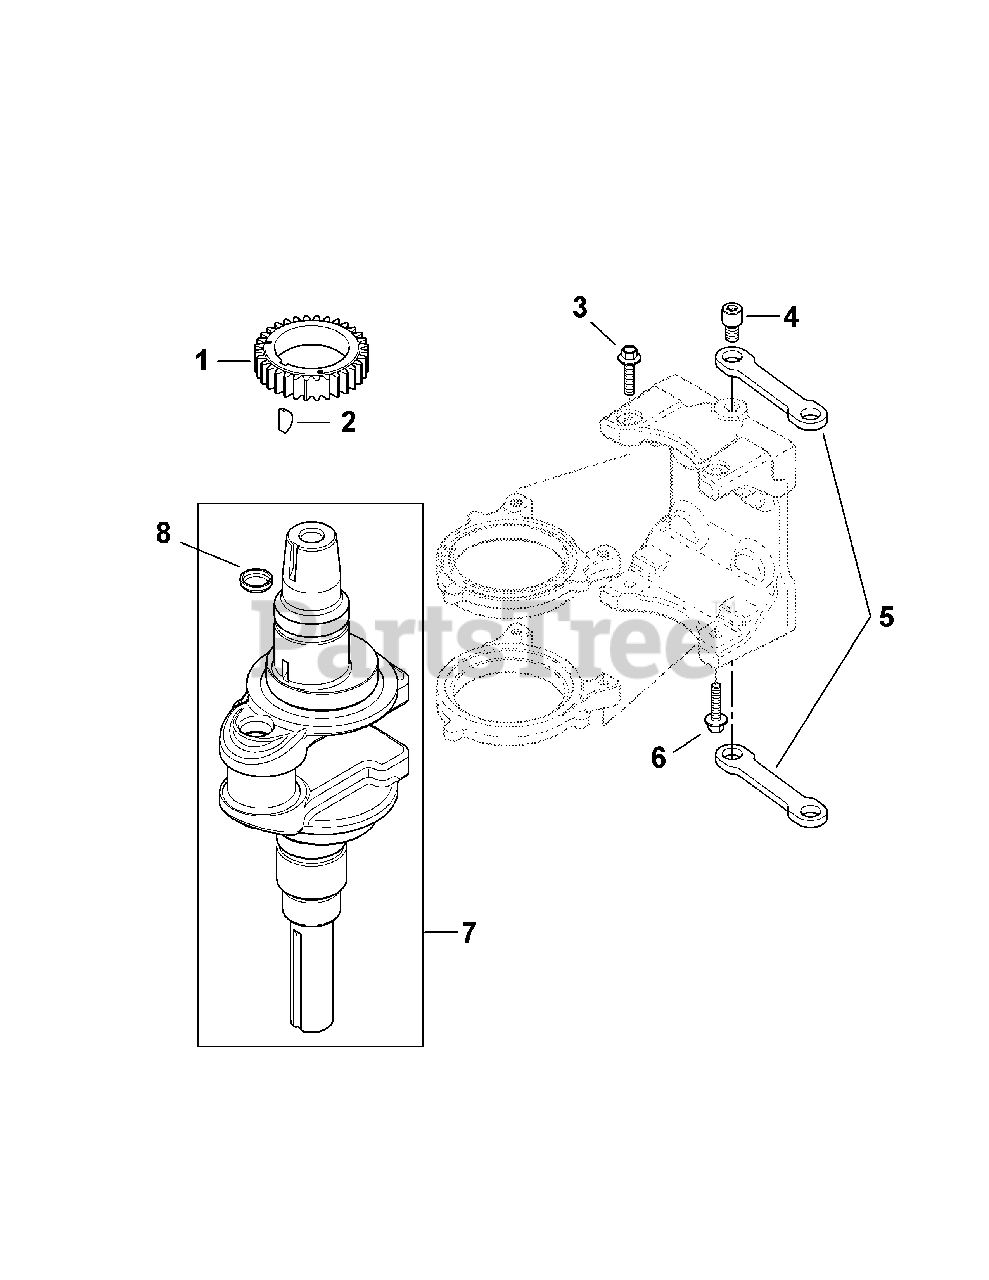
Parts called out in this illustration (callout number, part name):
1	Gear, Crankshaft
2	Key, 3/16" X 5/8"
3	Screw, Flg M6X1.0X25 - Discontinued
4	Screw, Link Pivot
5	Linkage, Balance Weight
6	Screw, Shoulder
7	Kit, Crankshaft Assembly
